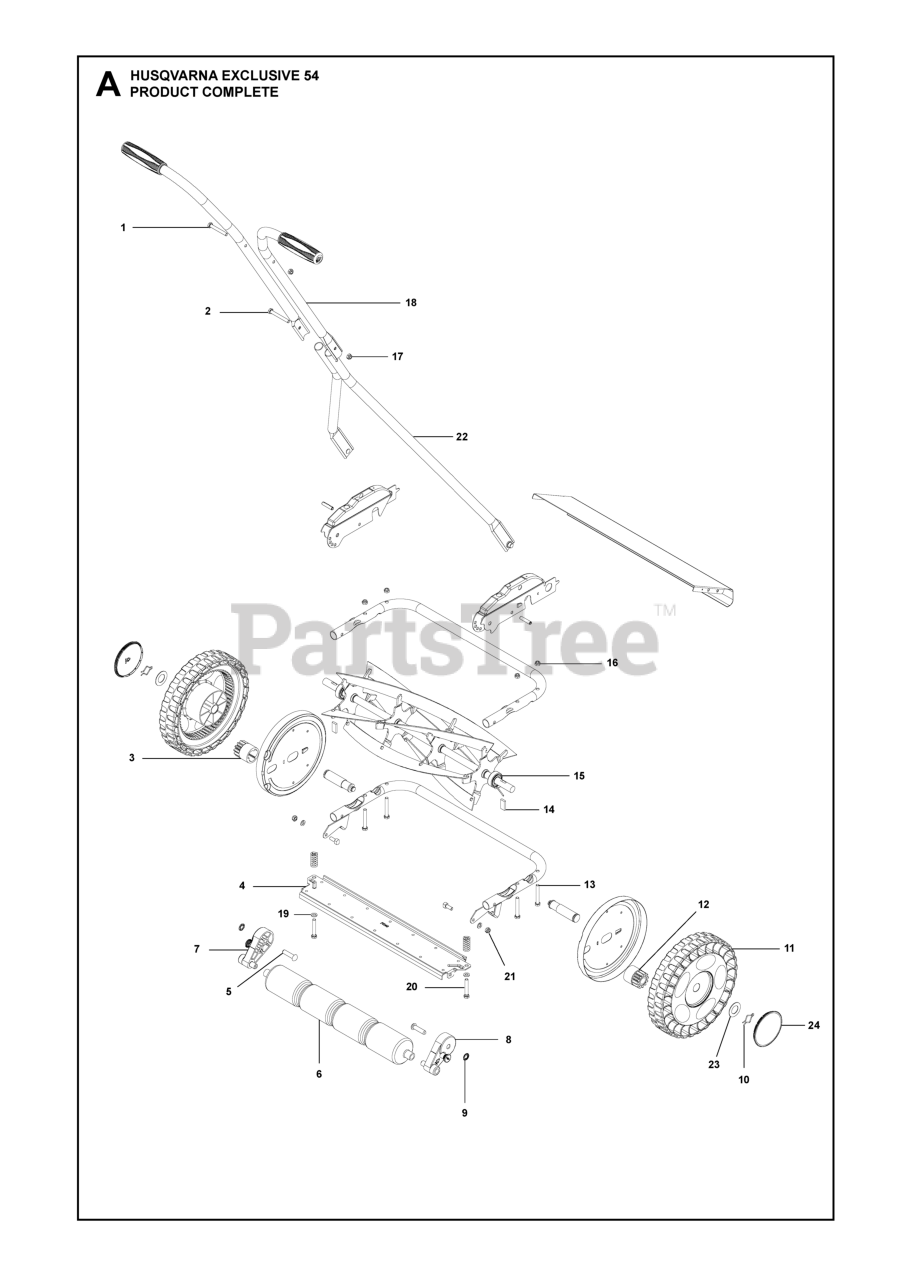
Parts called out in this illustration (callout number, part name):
2	SCREW M6X50
3	GEAR **
7	HOLDER
8	HOLDER
9	LOCKING WASHER
12	GEAR **
16	LOCKNUT M6
17	LOCKNUT M6
21	LOCKNUT M6
